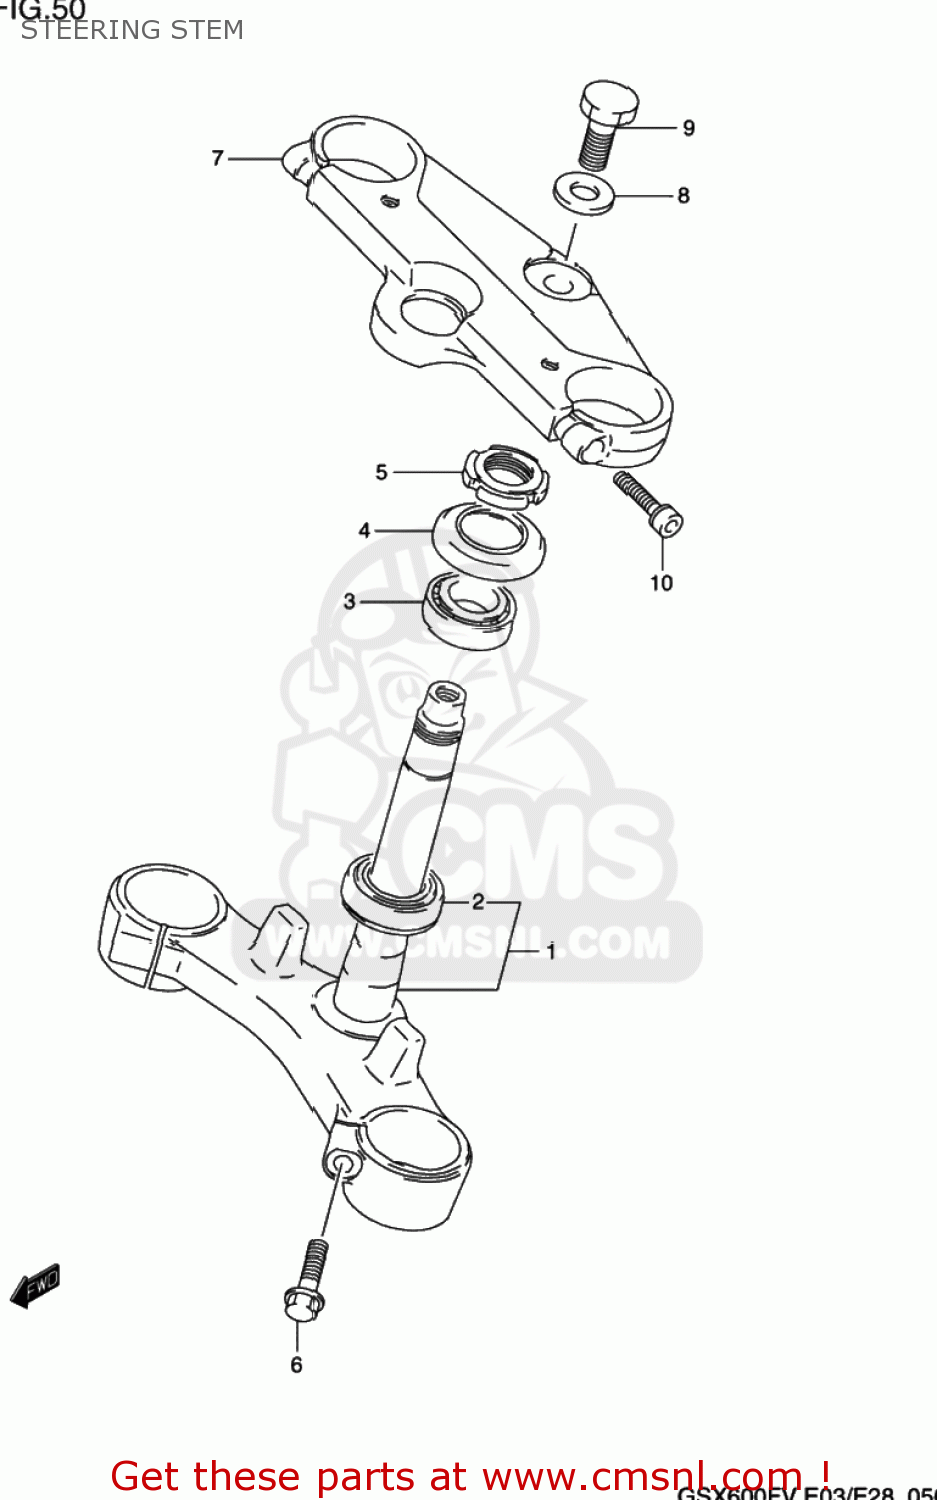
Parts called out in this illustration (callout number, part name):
1	STEM,STEERING
2	BEARING(30X55X17)
3	BEARING(25X47X15)
4	SEAL,STEERING UPR DUST
5	NUT,STEERING STEM(25X44X10)
6	BOLT
7	HEAD,STEERING STEM
8	WASHER,STEERING STEM
9	BOLT,STEERING STEM HEAD
10	BOLT
